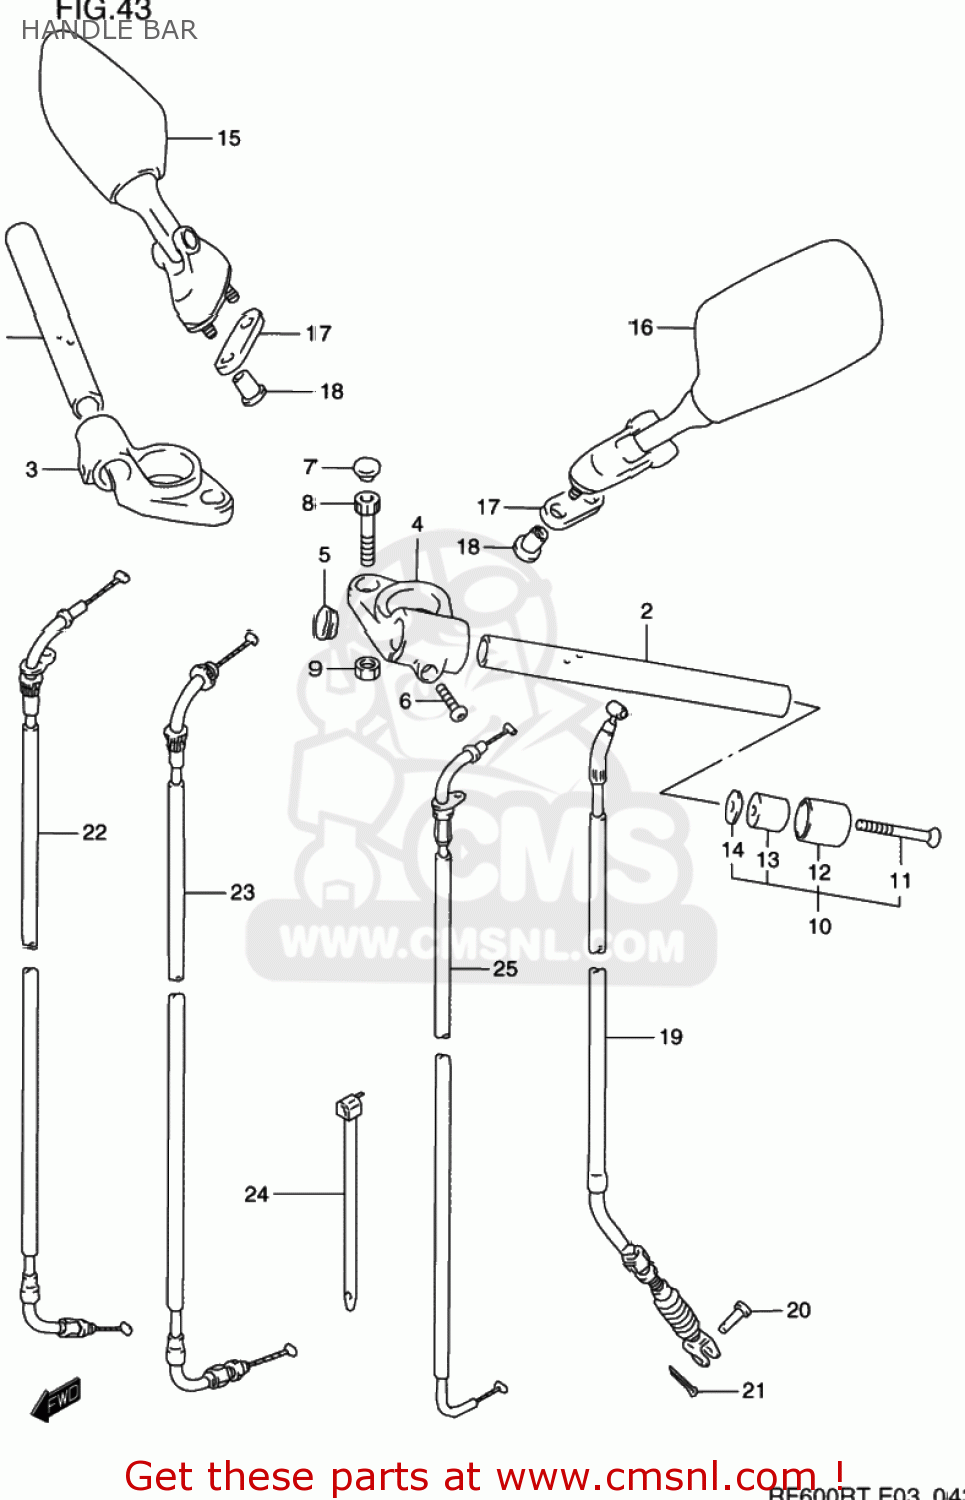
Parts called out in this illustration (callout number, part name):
1	HANDLEBAR
2	HANDLEBAR,L
3	HOLDER,HANDLEBAR,R
4	HOLDER,HANDLEBAR,L
5	PLUG(OD:22)
6	BOLT(8X25)
7	CAP(OD:12)
8	BOLT 10X50
9	NUT
10	BALANCER SET,HANDLEBAR
11	SCREW
12	CAP,BALANCER
13	BALANCER,HANDLEBAR
14	SPACER,BALANCER
15	MIRROR ASSY,RR VIEW,R
16	MIRROR ASSY,RR VIEW,L
17	CUSHION,RR VIEW MIRRORR
18	NUT,RR VIEW MIRROR
19	CABLE ASSY,CLUTCH
20	PIN(L:15)
21	PIN
22	CABLE ASSY,THROTTLE NO.1
23	CABLE ASSY,THROTTLE NO.2
24	CLAMP
25	CABLE COMP,STARTER
